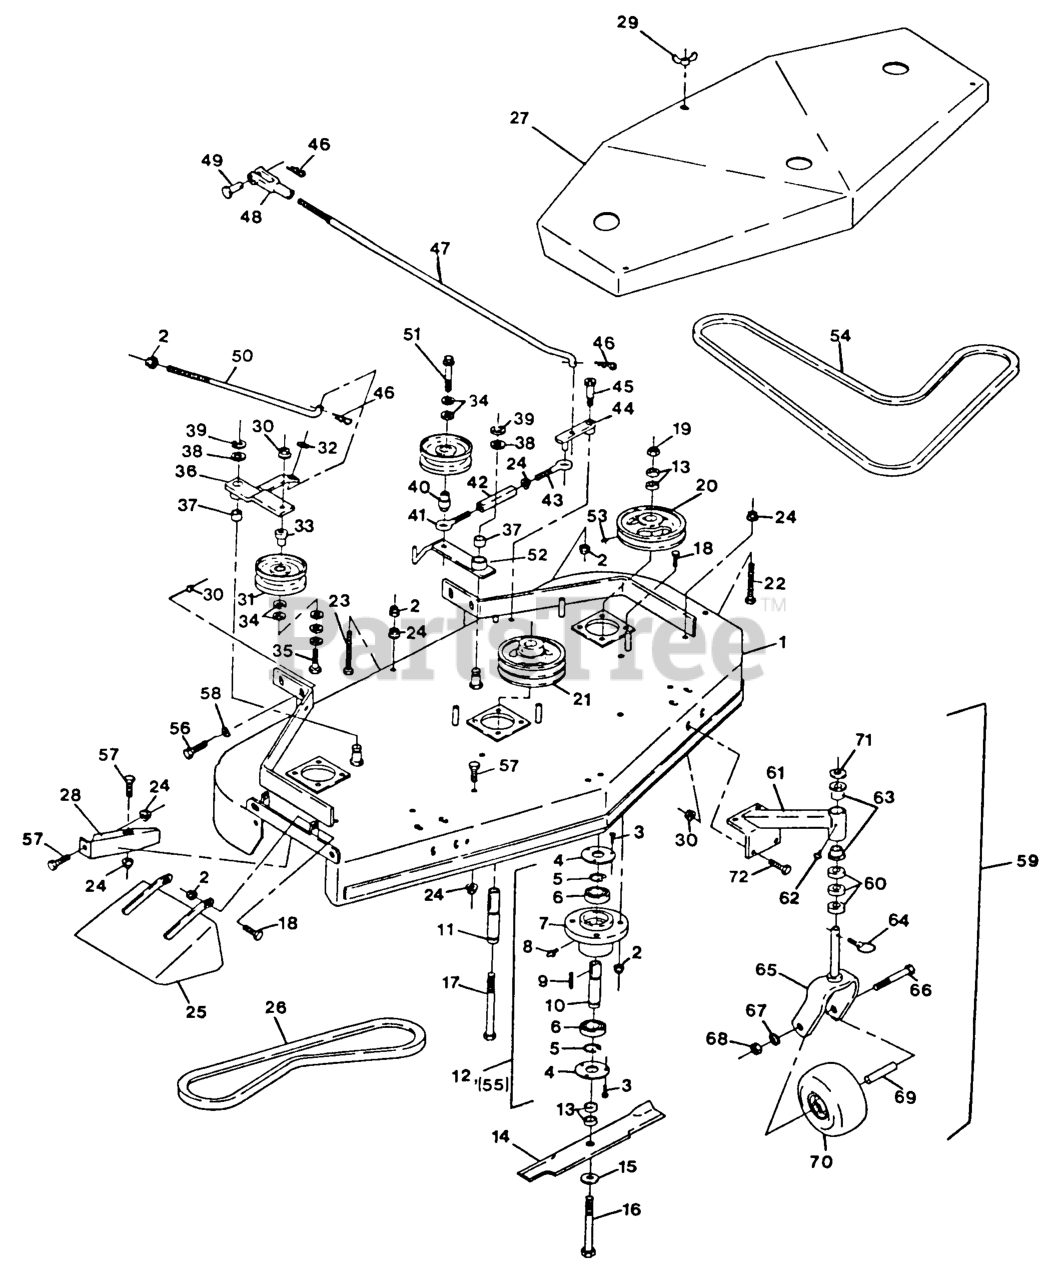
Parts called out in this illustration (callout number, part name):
3	SCRWMACH PHS
4	CAP,CUTTER HOUSING
5	RING,RETNG WLDS 5108-100
7	HOUSING,CUTTER
10	SPINDLE,CUTTER
12	HOUSING,CUTTER COMPLETE
17	SCREW-CAP, HH
20	PULLEY,CAST IRON
22	BOLT,TAP HH
23	BOLTTAP HH
26	BELT,FRONT DECK
28	BAFFLE-DOGLEG
33	BUSHING-IDLER
36	ARM,IDLER COMPLETE
37	BEARING,POWDERED METAL
38	WASHER-SPINDLE
40	BUSHING-ENGAGEMENT
41	EYEBOLT-THREAD, LH
42	BODY-TURNBUCKLE
43	EYEBOLT-THREAD, RH
45	BOLT,SHLDR KSKH
46	PIN-COTTER
47	ARM-ASSIST, LINKAGE
48	YOKE-ADJUSTABLE
49	PIN-CLEVIS
50	ROD,BELT TENSION
53	SCREW-SET
54	BELT,BLADE DRIVE
55	HOUSING,CUTTER COMPLETE
60	SPACER-CASTER
63	BEARING-FLANGED
71	WASHER-FLAT
